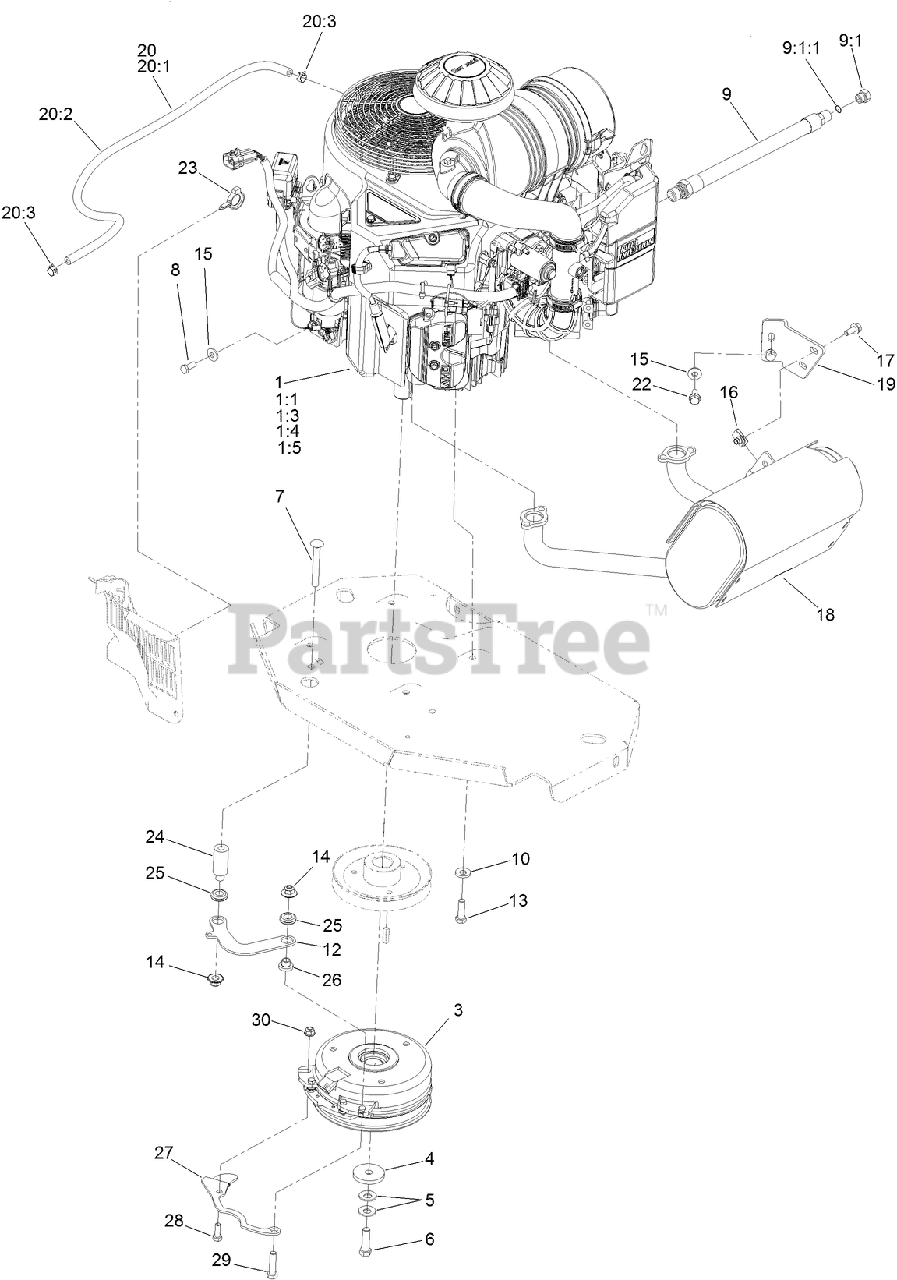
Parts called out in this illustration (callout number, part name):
1:1	KAWASAKI 49065-2078 ENGINE OIL FILTER
1:3	KAWASAKI 49019-0031 FUEL FILTER
1:4	KAWASAKI 11013-7039 SAFETY FILTER
1:5	KAWASAKI 11013-7038 AIR FILTER
3	CLUTCH KIT
4	WASHER-CLUTCH
5	WASHER-SPRING
6	SCREW-HH, W/LOCTITE
7	SCREW-CARR
8	SCREW-HH
9	ENGINE OIL DRAIN HOSE ASM
9:1	PLUG-HH
9:1:1	O-RING
10	WASHER-BELLEVILLE
12	LINK-ANCHOR, CLUTCH
13	SCREW-HH
14	NUT-FLANGE, NI
15	WASHER-SPRING
16	NUT-U
17	SCREW-HHF
18	MUFFLER
19	BRACKET-MUFFLER
20	FUEL LINE ASM
20:1	HOSE-FUEL
20:2	SLEEVE-THERMAL
20:3	CLAMP-HOSE
22	SCREW-HHF
23	CLAMP-HOSE
24	SPACER
25	GROMMET-RUBBER
26	SPACER
27	BELT-GUIDE
28	SCREW-HH
29	SCREW-HH
30	NUT-HF, NI
